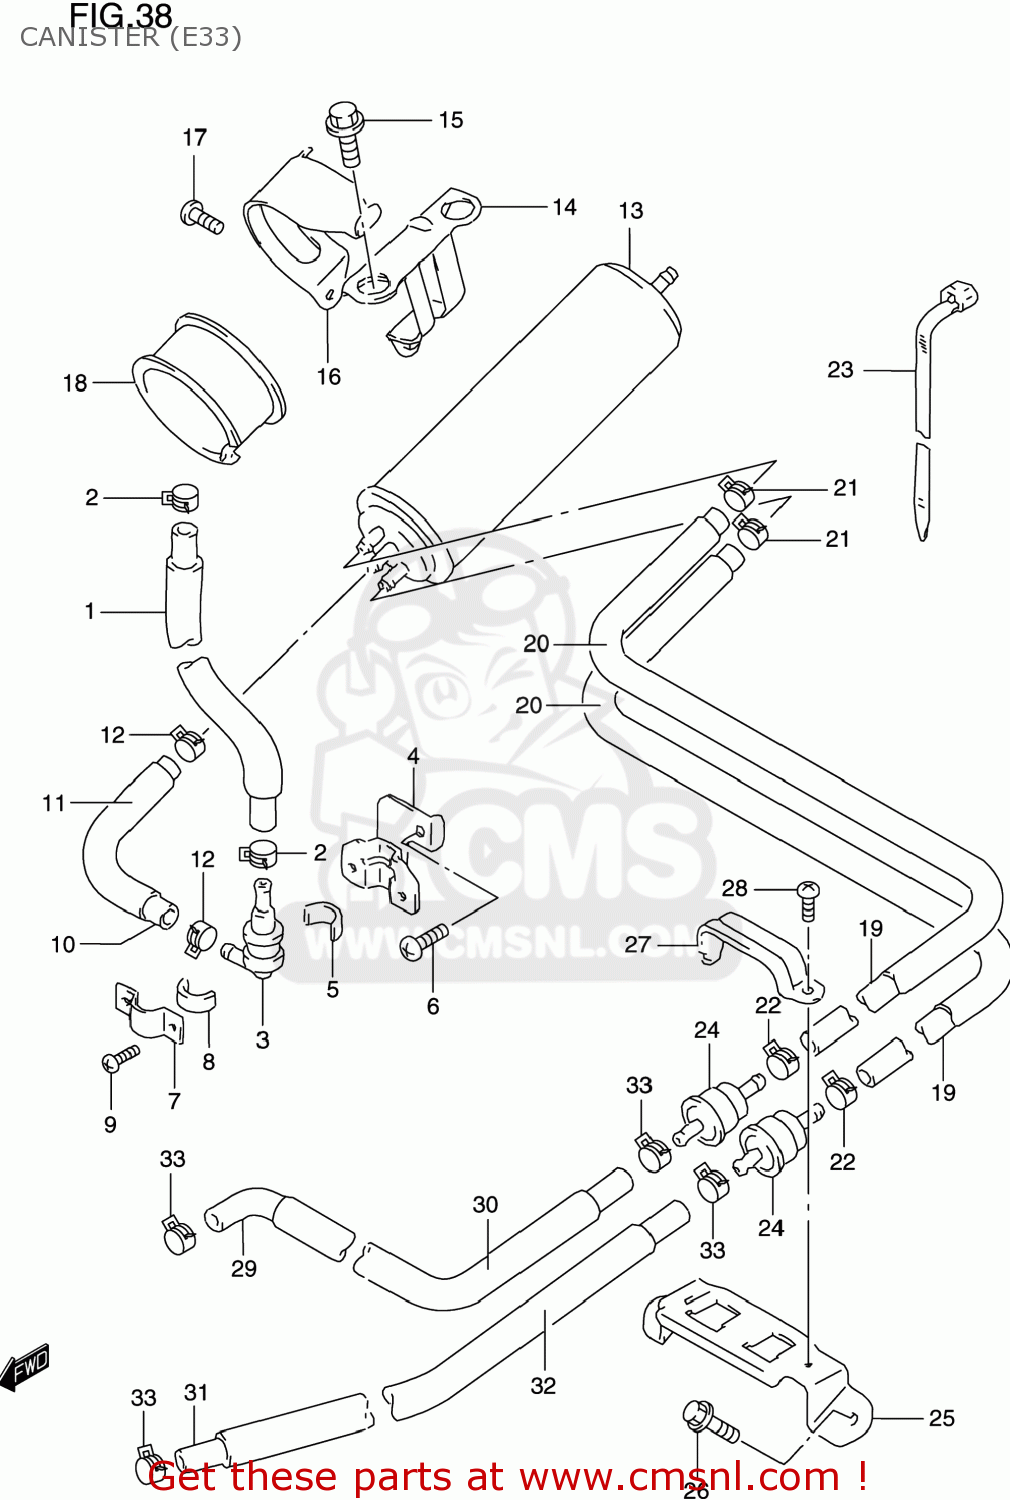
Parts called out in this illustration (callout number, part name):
1	HOSE(5.4X11.4X600)
2	CLIP
3	VALVE,FUEL TANK BREATHER
4	PLATE,BREATHER VALVE
5	CUSHION
6	SCREW 6X12
7	PLATE,FUEL TANK BREATHER NO.2
8	CUSHION
9	SCREW
10	HOSE(5.4X11.4X600)
11	PROTECTOR(14.5X15.5X600)
12	CLIP
13	CANISTER ASSY,CHARCOAL
14	BRACKET,CANISTER
15	BOLT(6X16)
16	HOLDER,CANISTER
17	SCREW 6X12
18	CUSHION,CANISTER
19	HOSE(5.4X11.4X600)
20	PROTECTOR(14.5X15.5X600)
21	CLIP
22	CLIP
23	CLAMP(L:125)
24	VALVE,CANISTER PURGE
25	BRACKET,CANISTER PURGE VALVE
26	BOLT
27	HOLDER,CANISTER PURGE
28	SCREW
29	HOSE(5.4X11.4X600)
30	PROTECTOR(14.5X15.5X600)
31	HOSE(5.4X11.4X600)
32	PROTECTOR(14.5X15.5X600)
33	CLIP
